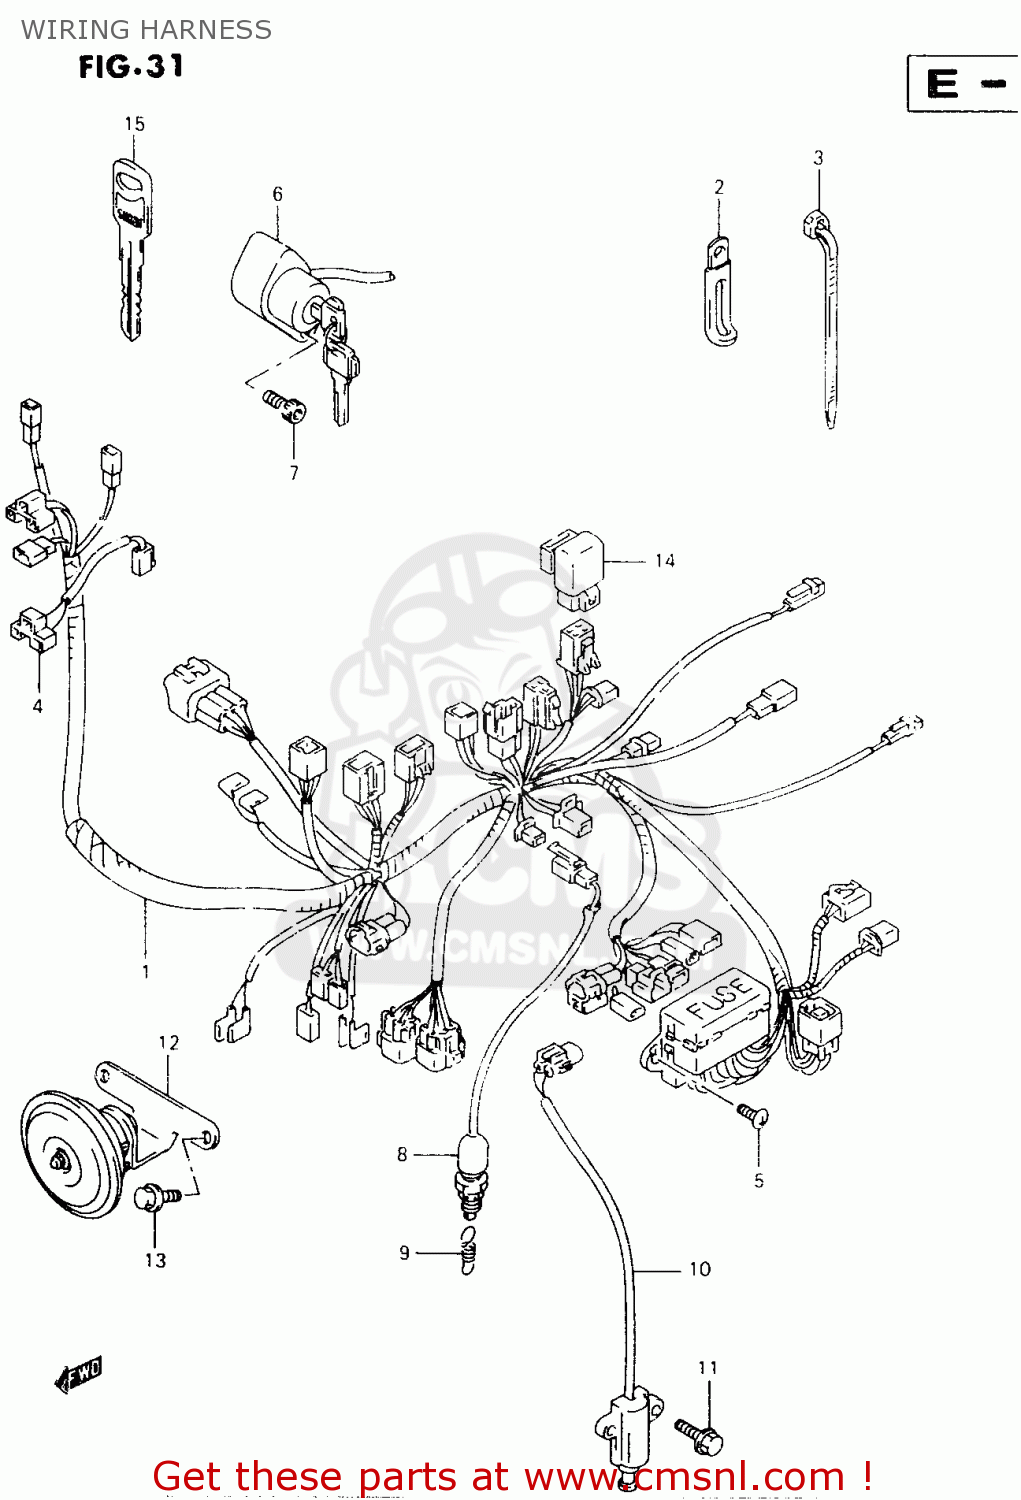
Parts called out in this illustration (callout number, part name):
1	HARNESS,WIRING
2	CLAMP(L:45)
3	CLAMP(L:95)
4	LEAD WIRE,HEADLAMP
5	SCREW 6X12
6	SWITCH ASSY,IGNITION
7	BOLT,OIL FILLE
8	SWITCH ASSY,STOP LAMP
9	SPRING
10	SWITCH ASSY,SIDE STAND WARNING
11	BOLT
12	HORN ASSY
13	BOLT
14	RELAY ASSY
15	KEY,BLANK
